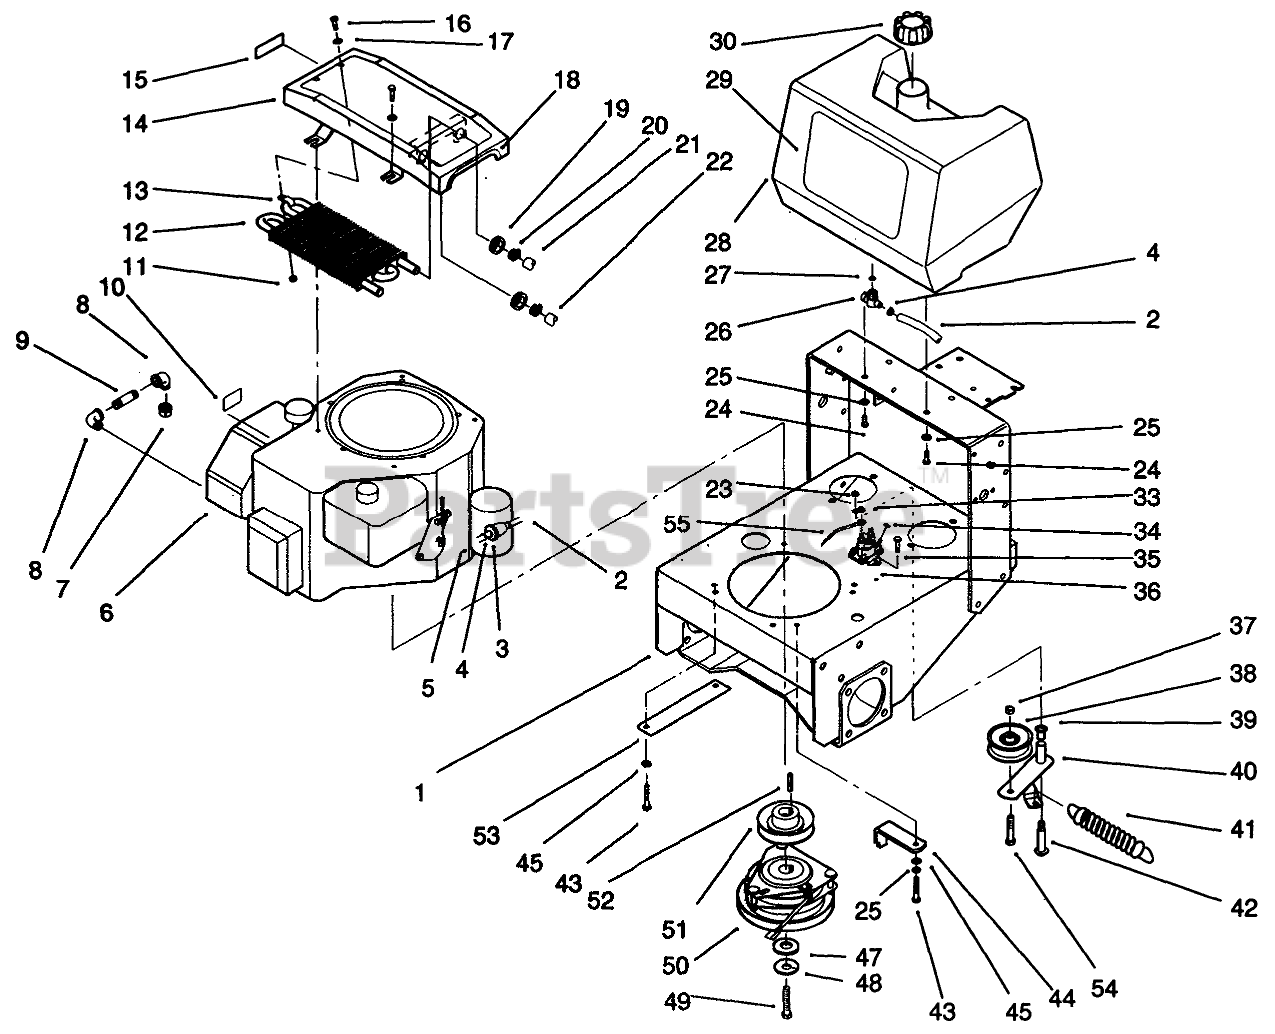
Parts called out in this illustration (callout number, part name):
1	Frame
2	HOSE-FUEL
3	FILTER-FUEL
4	CLAMP-HOSE
5	HOSE-FUEL
6	Engine-14 H.P. Kohler
7	CAP-PIPE
8	ELBOW-STREET, 90 DEG
9	NIPPLE
10	DECAL-SURFACE, HOT
11	NUT-LOCK, NI
12	Cooler-Oil
13	CLAMP-R
14	Mount-Cooler
15	DECAL-FUEL SHUT OFF
16	SCREW-HH
17	WASHER-FLAT
18	TRIM-MOUNT, COOLER
19	GROMMET
20	CLAMP-HOSE
21	HYDRAULIC HOSE ASM
22	HYDRAULIC HOSE ASM
23	NUT-LOCK
24	SCREW-HH
25	WASHER-LOCK
26	VALVE-FUEL
27	O-RING
28	FUEL TANK
29	Decal-Toro
30	GAS CAP ASM
33	NUT-KEPS
34	NUT-KEPS
35	SCREW-HWH
36	Solenoid
38	PULLEY
39	BUSHING-FLANGE
40	Idler Assembly
41	SPRING
42	BOLT-WHEEL
43	SCREW-HH
44	Retainer-Clutch
45	WASHER-PLAIN
47	WASHER-CLUTCH
48	WASHER-LOCK
49	SCREW-CLUTCH
50	CLUTCH/BRAKE
51	Pulley
52	KEY-SQUARE
53	Guard-Pulley
54	SCREW-HH
55	WIRE-SOLENOID/STARTER
